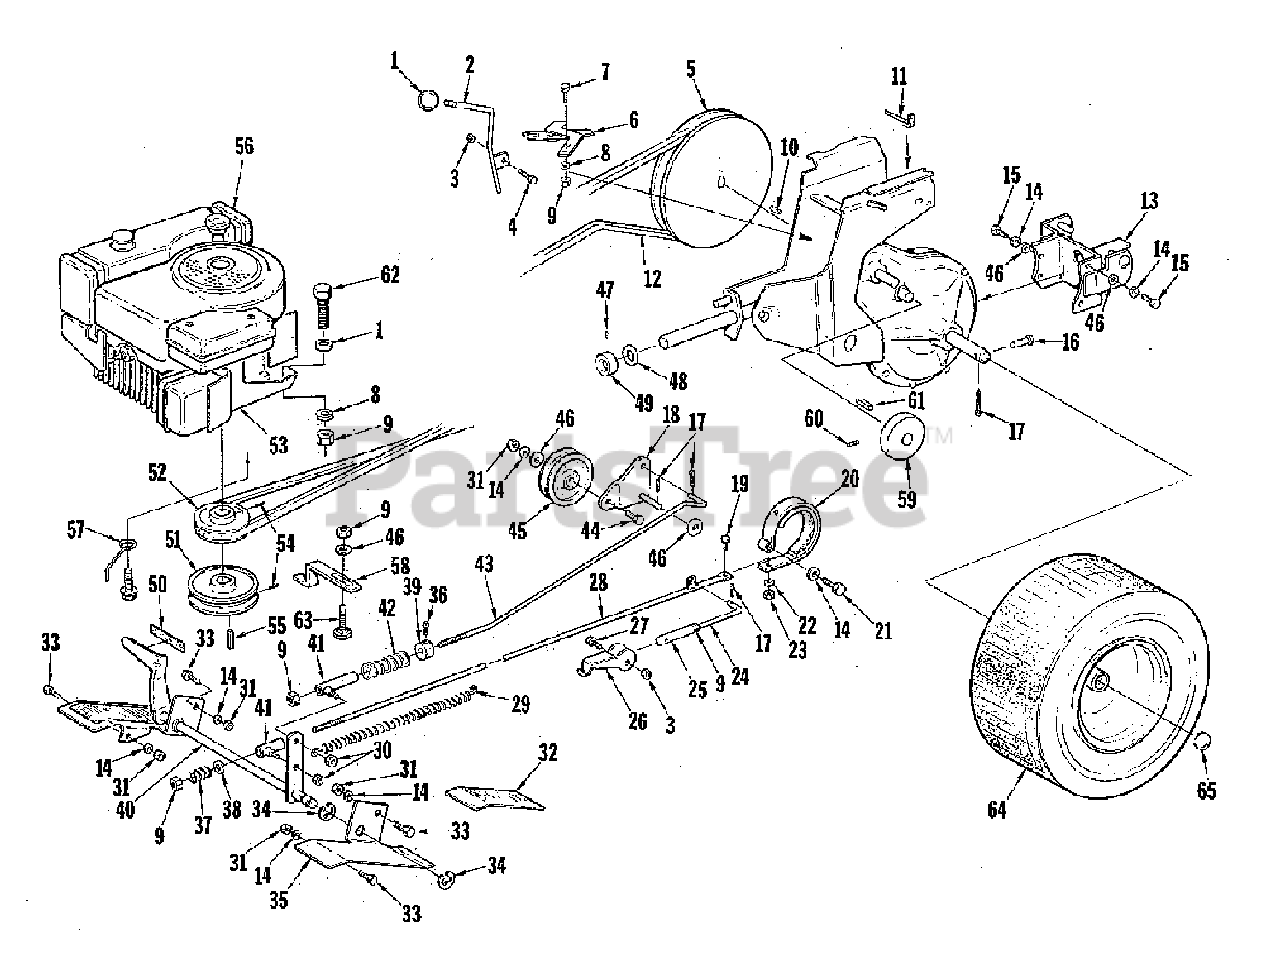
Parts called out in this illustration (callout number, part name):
2	ROD ASSEMBLY, Shift
3	NUT, Lock, Hex Fin, 1/4-20
4	CAPSCREW, Hex Head, 1/4-20 x 3/4
5	PULLEY, Transmission
6	PIVOT ASSEMBLY
7	CAPSCREW, 5/16-18 x 3/4
9	NUT, Hex, 5/16-18
11	CLIP, "J", Open
12	BELT, "V", Drive
13	DRAWBAR & HITCH ASSEMBLY
14	LOCKWASHER, 3/8
15	CAPSCREW, 3/8-16 x 3/4
18	BRACKET ASSEMBLY, Pulley
19	CAPSCREW, Hex Head, 1/4-20 x 1/2
20	BAND ASSEMBLY, Brake
21	CAPSCREW, Hex Head, 3/8-16 x 1-1/2
22	LOCKWASHER, 1/4
23	NUT, Hex, 1/4-20
24	ROD, Parking Brake
27	CAPSCREW, Hex Head, 1/4-20 x 1
28	ROD ASSEMBLY, Brake
29	SPRING, Return
30	NUT, Hex, Lock
31	NUT, Hex, 3/8-16
32	COVER, Foot Rest
35	FOOT REST, L.H.
36	SETSCREW, Square Head, 1/4-20 x 3/8
37	SPRING, Conical
40	SHAFT ASSEMBLY, Clutch
41	GUIDE ASSEMBLY, Rod
42	SPRING, Compression
44	CAPSCREW, Hex Head, 3.8-16 x 1-1/4
45	PULLEY, Idler
47	SETSCREW, Square Head, 15/16-18 x 1/2
51	PULLEY, Engine, Large
52	PULLEY, Engine, Small (T-8)
52	PULLEY, Engine, Small (T-7)
53	SHIELD, Heat
54	SETSCREW, Hex Socket (T-8)
54	SETSCREW, Hex Socket (T-7)
60	SETSCREW, 5/16-18 x 1/2 Socket Head
62	SCREW, Taptite Hex, 3/8-16
64	WHEEL & TIRE, Rear (T-7)
64	WHEEL & TIRE, Rear (T-8)
65	PLUG, Button
